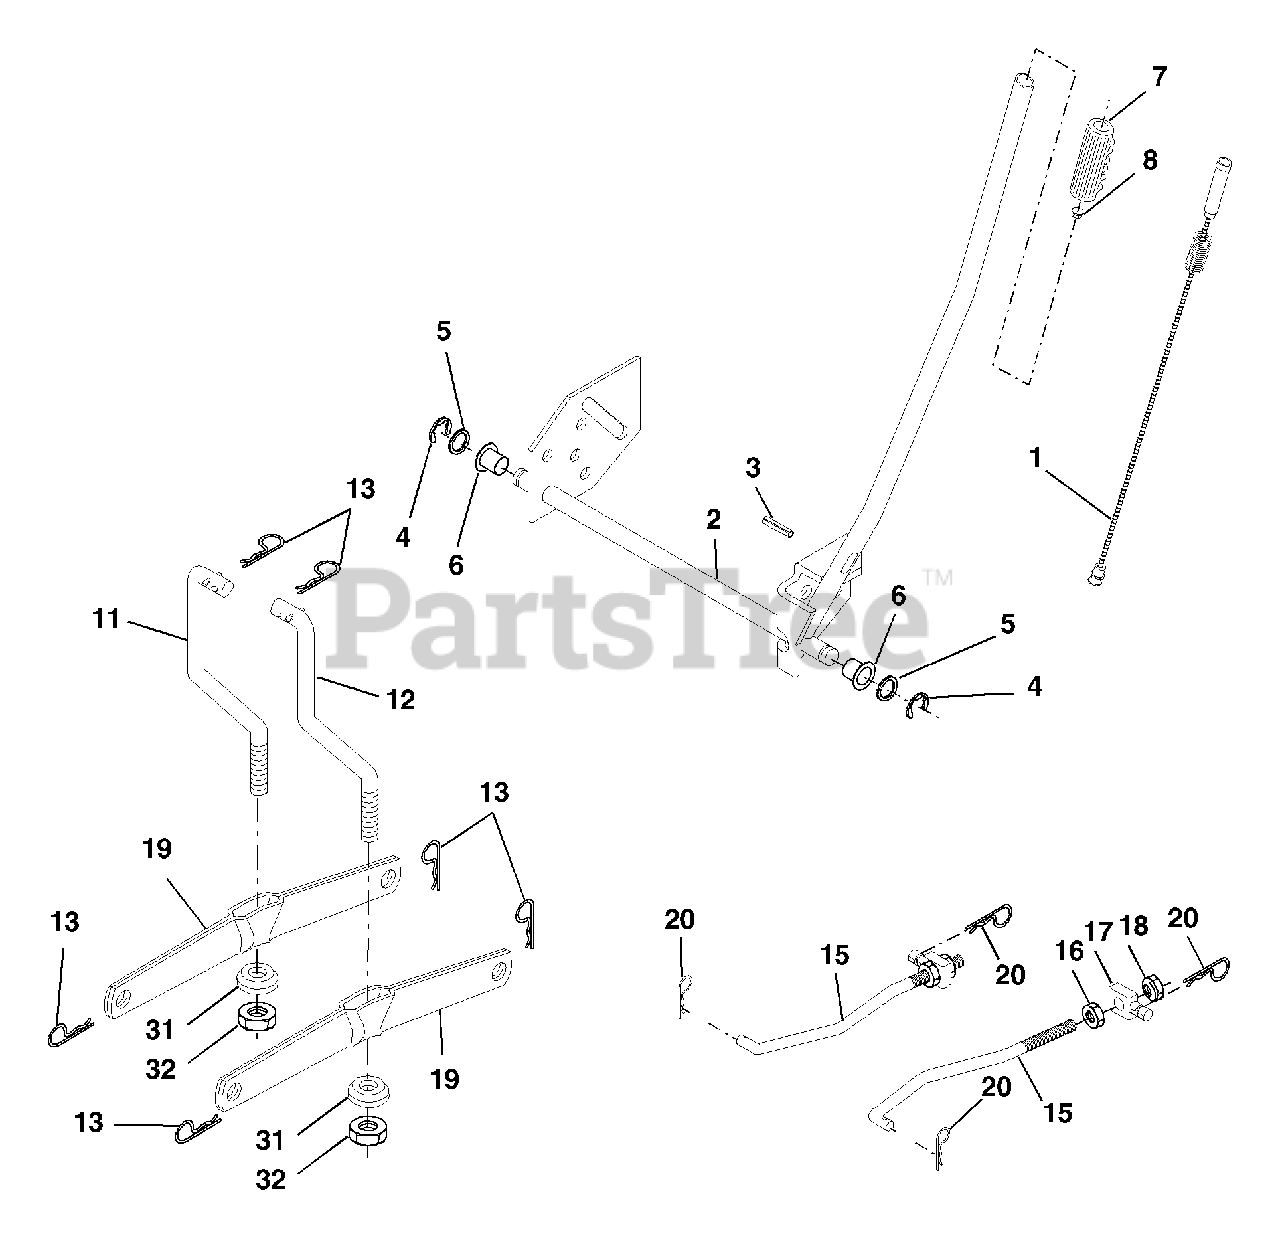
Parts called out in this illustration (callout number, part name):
1	Wire Asm Inner W/plunger
2	Shaft Asm Lift
3	Pin Groove 1 500 Zinc
4	E Ring #5133-62
5	Washer Pltd 21/32 X 1 X 21ga
6	Bearing Nylon Blk 629 Id
7	Grip Handle Fluted Blk
8	Button Plunger Red
11	Link Lift LH
12	Link Lift RH
13	Retainer Spring
15	Link Front
16	Nut Jam Hex 1/2-13 Unc
17	Trunnion Blk Zinc
18	Nut Lock w/Wsh 1/2-13 UNC
19	Arm Suspension Rear
20	Retainer Spring Zinc
31	Bearing Pvt Lift
32	Nut Crownlock 3/8-24
